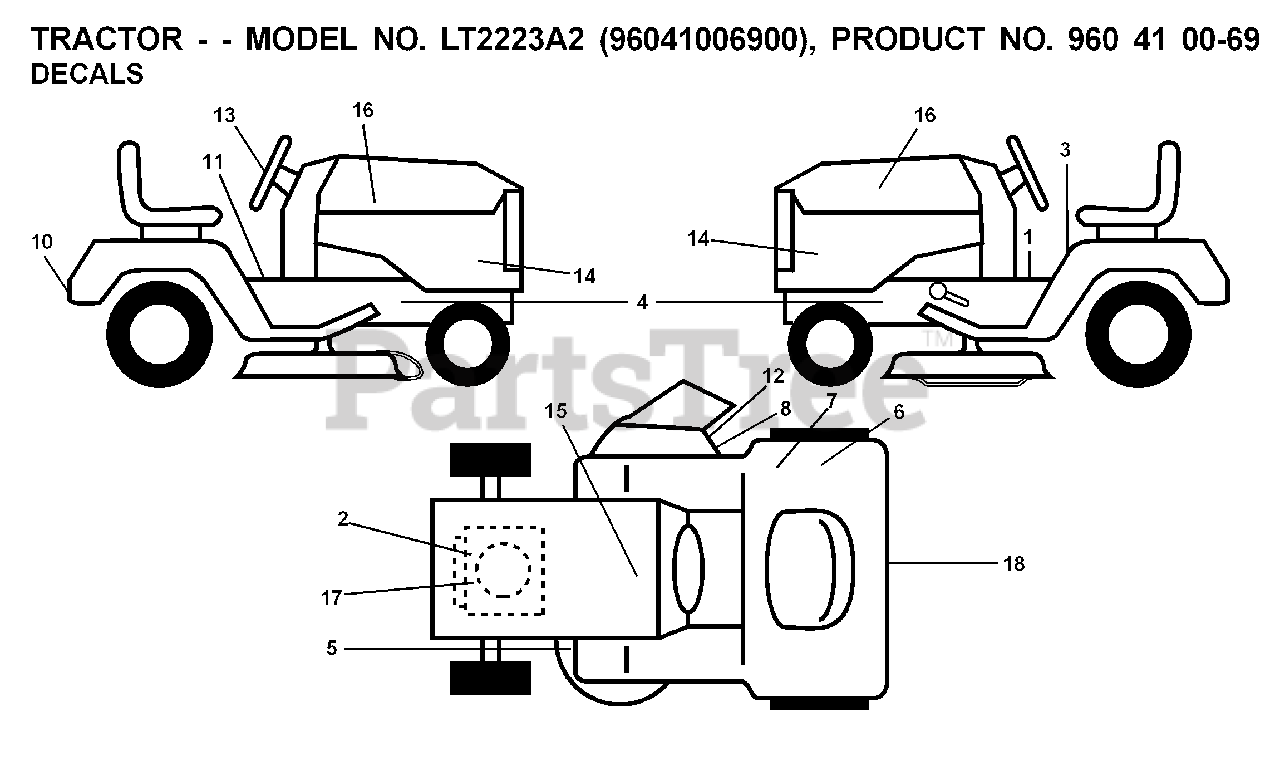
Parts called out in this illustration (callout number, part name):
1	DECAL PARK BRAKE
5	DECAL V BELT SCHEMATIC
7	DECAL.80 DBA.AUSTRALIA
8	DECAL, DEFLECT WARNING
12	DECAL.INTERNATIONL.CUTFINGER
15	DECAL BTRY SYMBOLS
